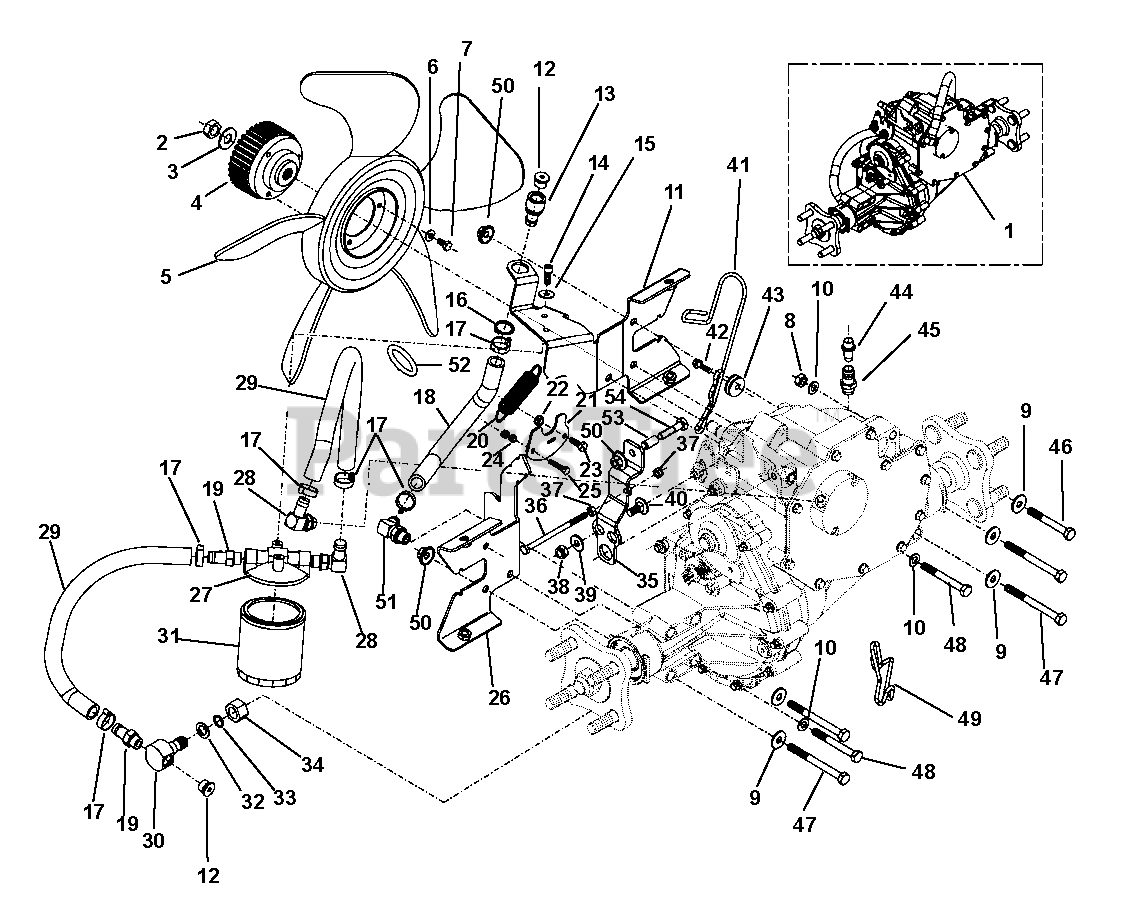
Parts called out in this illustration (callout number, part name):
1	Hydrostat
2	Special Nut
4	Pulley, Hydro
5	Fan
6	Spacer, 1.03 x 1.38 x .184
7	Bolt, Hex D933 M6 x 12
8	Nut, Hex D934 M8
9	Washer, M8
10	Washer, 31181 M8
12	Plug, Steel (with Seal)
13	Support, Tube
14	Screw, UNC 1/4" x 5/8"
15	Washer, M6
16	Circlip, D471 20 1,20
17	Hose Clamp
20	Tension Spring 2.0/17.5 x 87
22	Nut, Lock D985 M6
23	Bolt, Hex D933 M6 x 18
24	Nut, Lock
25	Bolt, Hex D933 M5 x 25
27	Filter Case
30	Connection, Threaded
32	Supporting Ring
34	Nut, Hex
35	Lever, Forward
36	Bolt, Hex D931 M6 x 100
37	Nut, Hex D934 M6
38	Nut, Lock D985 M8
39	Washer, BN737 8,4 x 20 x 2
40	Screw, Truss Head D603 M8 x 20
41	Spring Clip
42	Screw, DIN7500/D M5 x 20
44	Breather
45	Fitting
46	Bolt, Hex D931 M8 x 65
47	Bolt, Hex D931 M8 x 90
48	Nut, Lock D985 M6
49	Spring Clip
50	Nut, Lock M8
51	Fitting, 60-Degree
53	Pin, Roll
54	Bolt, Hex D931 M8 x 35
